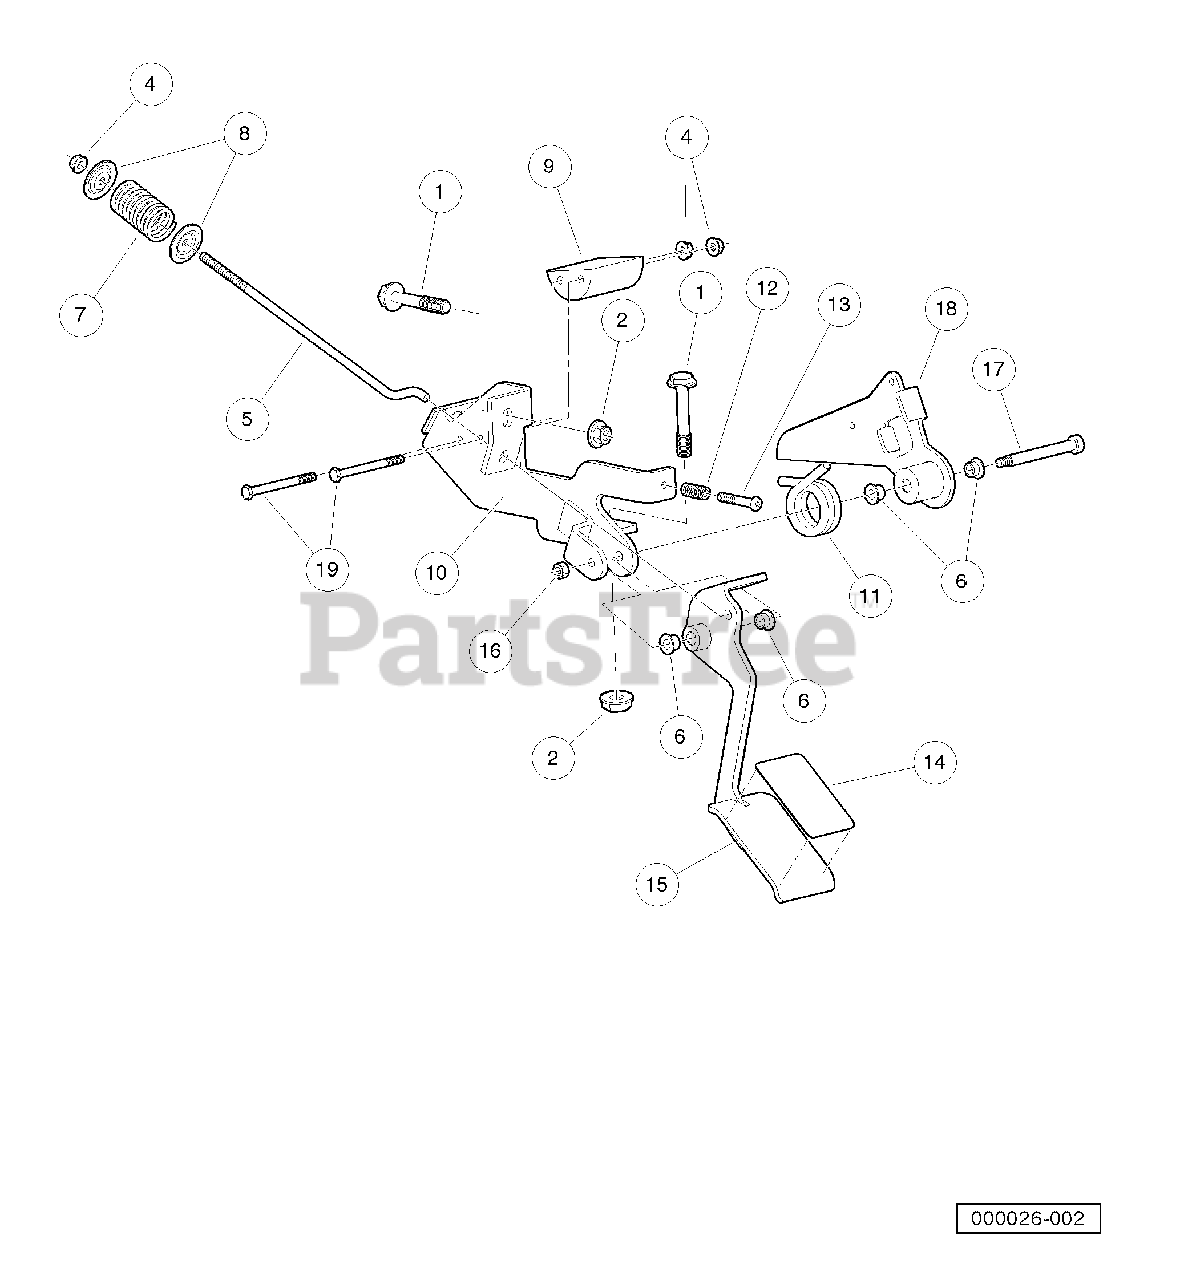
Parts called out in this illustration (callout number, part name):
1	Bolt Flanged Head, M8 X 1.25 X 65
2	Lock Nut, Flg M8 X 1.25 Nylon
3	Asm, Accelerator Pedal
4	Nut-m6x1.0 Flng All Mtl Lock
5	Pullrod, Spring, Compression
6	Bushing, Greaseless
7	Spring, Comp, Pedal, Pullrod
9	Guide, Cable, Accelerator
10	Weldment, Bracket, Pedal
11	Spring, Torsion
12	Spring, Stop, Pedal
13	Bolt, Stop, Pedal
14	Pad, Grip Tape, Accelerator
15	Weldment, Pedal, Accelerator
16	Nut M6x1 Mech Def Center
17	Bolt, Shoulder, M8 X 70, Hc
18	Weldment, Lever, Lost Motion
19	Bolt, M6 X 1 X 70
